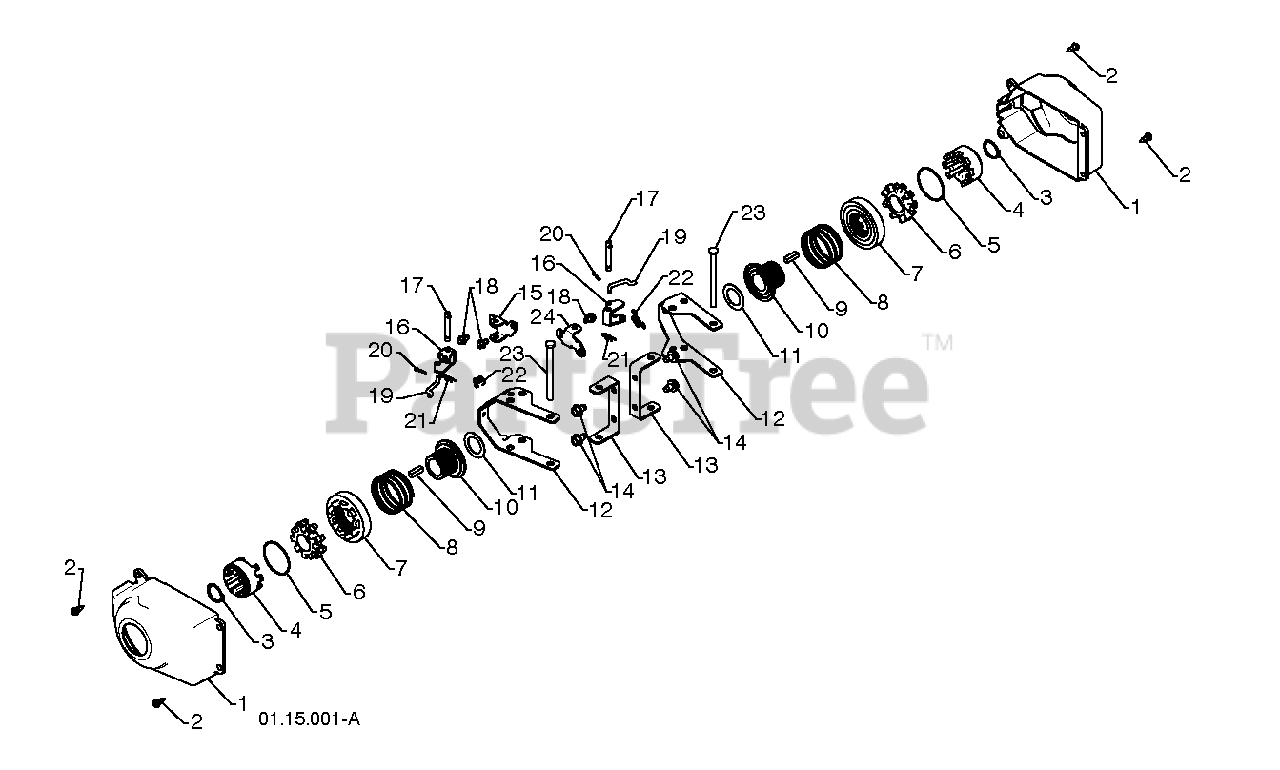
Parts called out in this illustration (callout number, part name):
1	COVER, POWER STEERING
2	SCREW, HEX HEAD, TAPPING
4	DRIVER WHEEL
5	RING, WIRE RETAINER
6	LOBE WHEEL
7	SLIDE.CLUTCH
8	SPRING, CLUTCH SLIDE
9	KEY, SQUARE 1/4 X .875
10	LOBE.AXLE
11	WASHER TRUST 1"
12	STEERING YOKE
13	BRACKET
15	BRKT.STEER.PIVOT.RH
16	BELLCRANK.STEER
17	PIN, STEERING BELLCRANK
19	LINK.STEER.YOKE
20	RETAINER CLIP
21	RETAINER CLIP PM
22	SPRING LATCH
23	PIN, STEERING LEVER
24	CONTROL SHAFT
